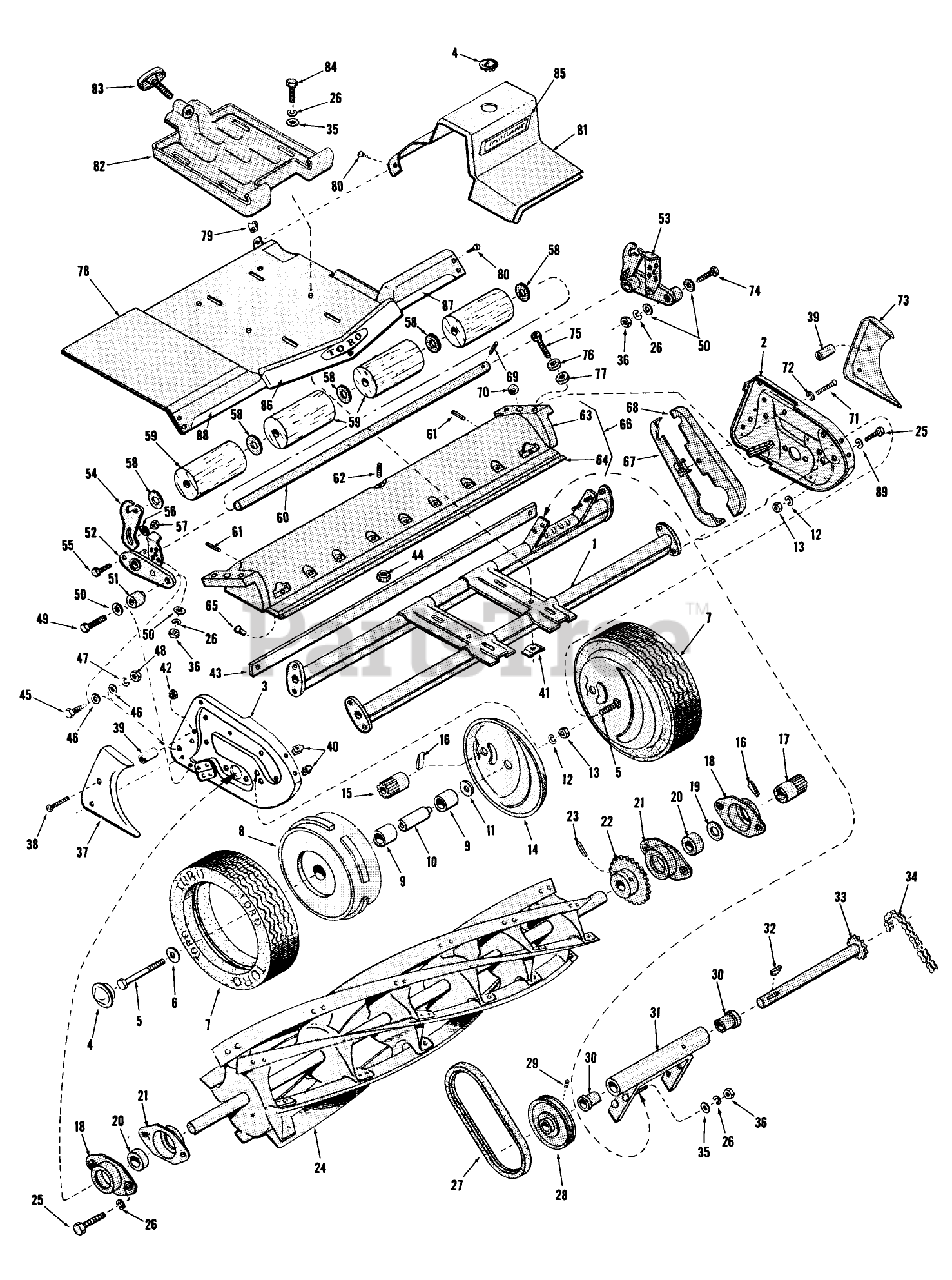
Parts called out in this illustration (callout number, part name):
1	Main Frame
2	Side Plate, Left
3	Side Plate, Right
6	WASHER
7	10-1/2 TIRE
8	Wheel w/Bush. Ref. 9
9	BUSHING
10	Spindle, Wheel
11	9/16ID X 032 WASHER
12	WASHER-LOCK
13	NUT-JAM
14	Wheel Cover
15	Reel Pinion, Right
16	RATCHET DOG
17	Reel Pinion, Left
18	Bearing Holder, Outer
19	19/32X 030 EX MED RNG
20	Bearing
21	Bearing Holder, Inner
22	Reel Drive Sprocket
23	PIN-ROLL
24	Reel Assembly
25	SCREW-HH
26	WASHER-LOCK/SP
27	Drive Belt
28	Pulley
29	SCREW-SET, HSH
30	BUSHING
31	Countershaft Housing w/Bush. Ref. 30
32	KEY-WOODRUFF
33	Countershaft & Sprocket Assembly
34	Drive Chain
35	WASHER-PLAIN
36	NUT-HEX
37	Side Plate Cover, Right
38	Screw, 10-24 x 1-1/8"
39	Spacer
40	NUT-TYPE J
41	Engine Mounting Slide
42	NUT-HEX
43	Adjusting Bar
44	NUT-LOCK NI
46	WASHER-FLAT
47	WASHER-LOCK
48	NUT-HEX
49	SCREW-HH
50	7/16 SPRING WASHER
51	Spacer
52	Adjusting Arm, Right
53	Adjusting Arm, Left
54	Grass Catcher Hook
55	SCREW-HH
56	WASHER-FLAT
57	NUT-HEX
58	Washer
59	Roller Section
60	Roller Shaft
61	PIN-ROLL
62	Set Screw, 5/16" N.F. x 1/2"
63	Bed Bar Assy., Incl. Refs. 43, 44, 61 & 62
64	Bed Knife
65	Rivet, Bed Knife
66	Bed Bar Assy., Incl. Refs. 61 thru 65 & Ref.44
67	Chain Guard, Rear
68	Chain Guard, Front
69	PIN-SPRING
70	Ball
71	SCREW
72	WASHER-LOCK
73	Side Plate Cover, Left
74	SCREW-HH
75	ADJ SCREW
76	U SPHER WASHER
77	L SPHER WASHER
78	Platform
79	Special Screw
80	Screw, #10 x 5/8" Self Tap
81	Cover, Countershaft
82	Adapter Plate
83	Clamp Assy.
84	SCREW-HH
85	Decal, Countershaft Cover
86	Chrome Cal, Center
87	Bumper Chrome Cal, Left
88	Bumper Chrome Cal, Right
89	WASHER-LOCK
